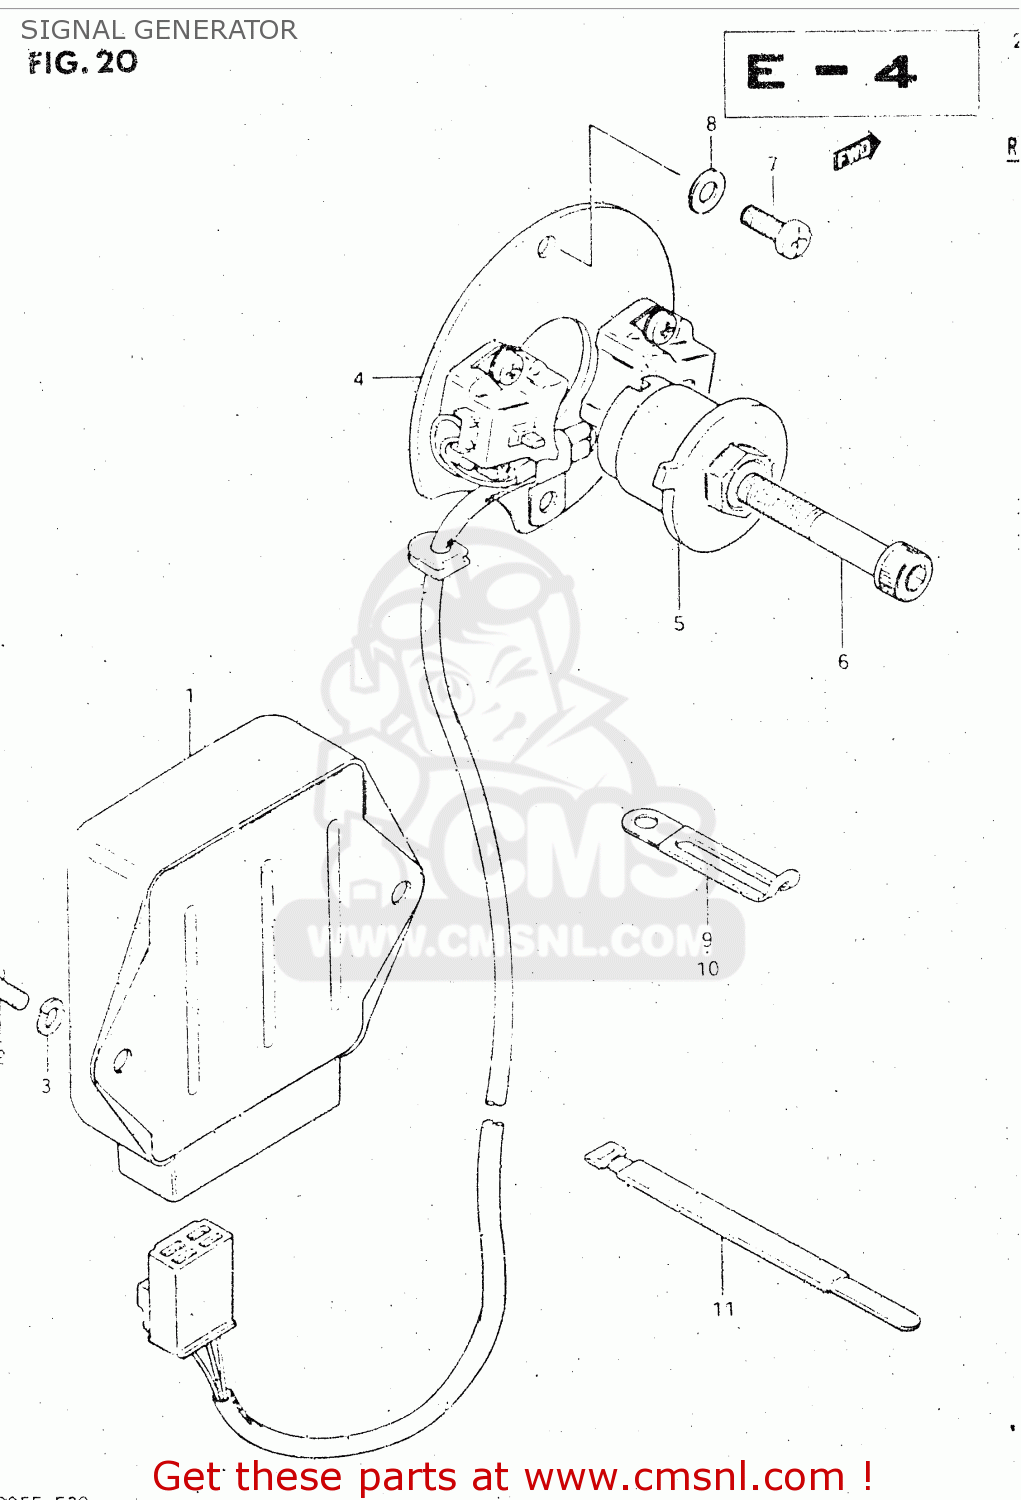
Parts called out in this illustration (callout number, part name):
1	IGNITER UNIT ASSEMBLY
2	SCREW 6X12
3	LOCK WASHER
4	GENERATOR ASSY,SIGNAL
5	ROTOR,SIGNAL
6	BOLT
7	SCREW(5X12)
8	WASHER(5.5X10X0.8)
9	CLAMP L:35
10	CLAMP
11	CLAMP
